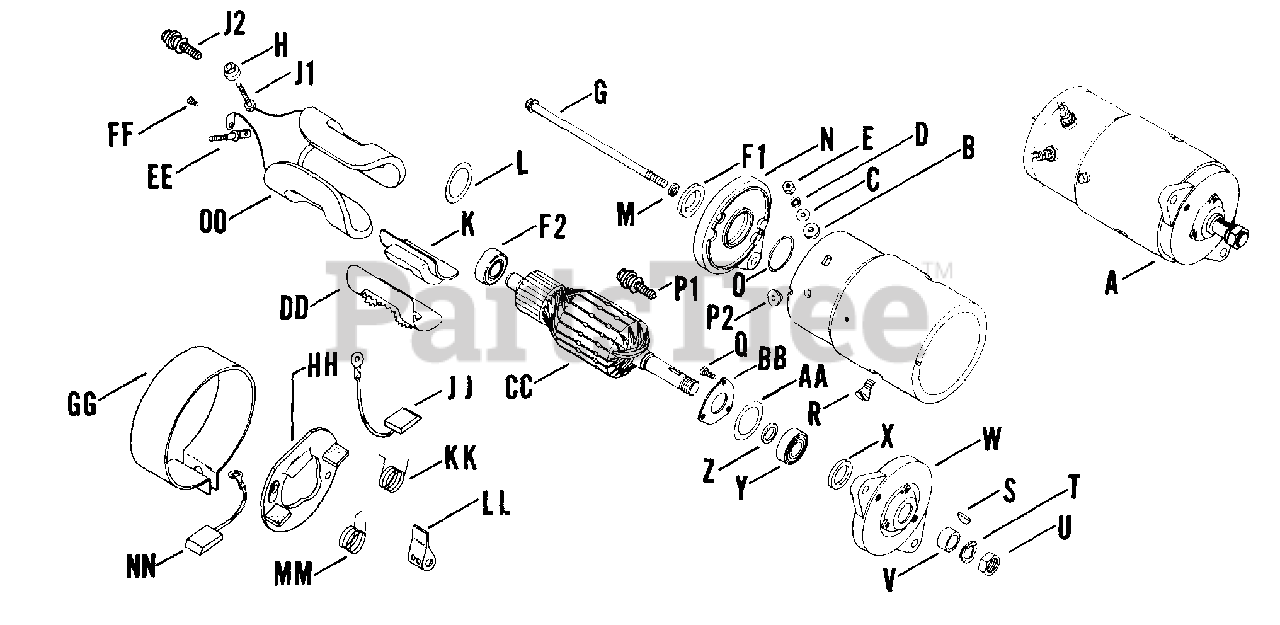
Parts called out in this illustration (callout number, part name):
U	NUT - DISCONTINUED
Y	BEARING - DISCONTINUED
GG	Cover, band
